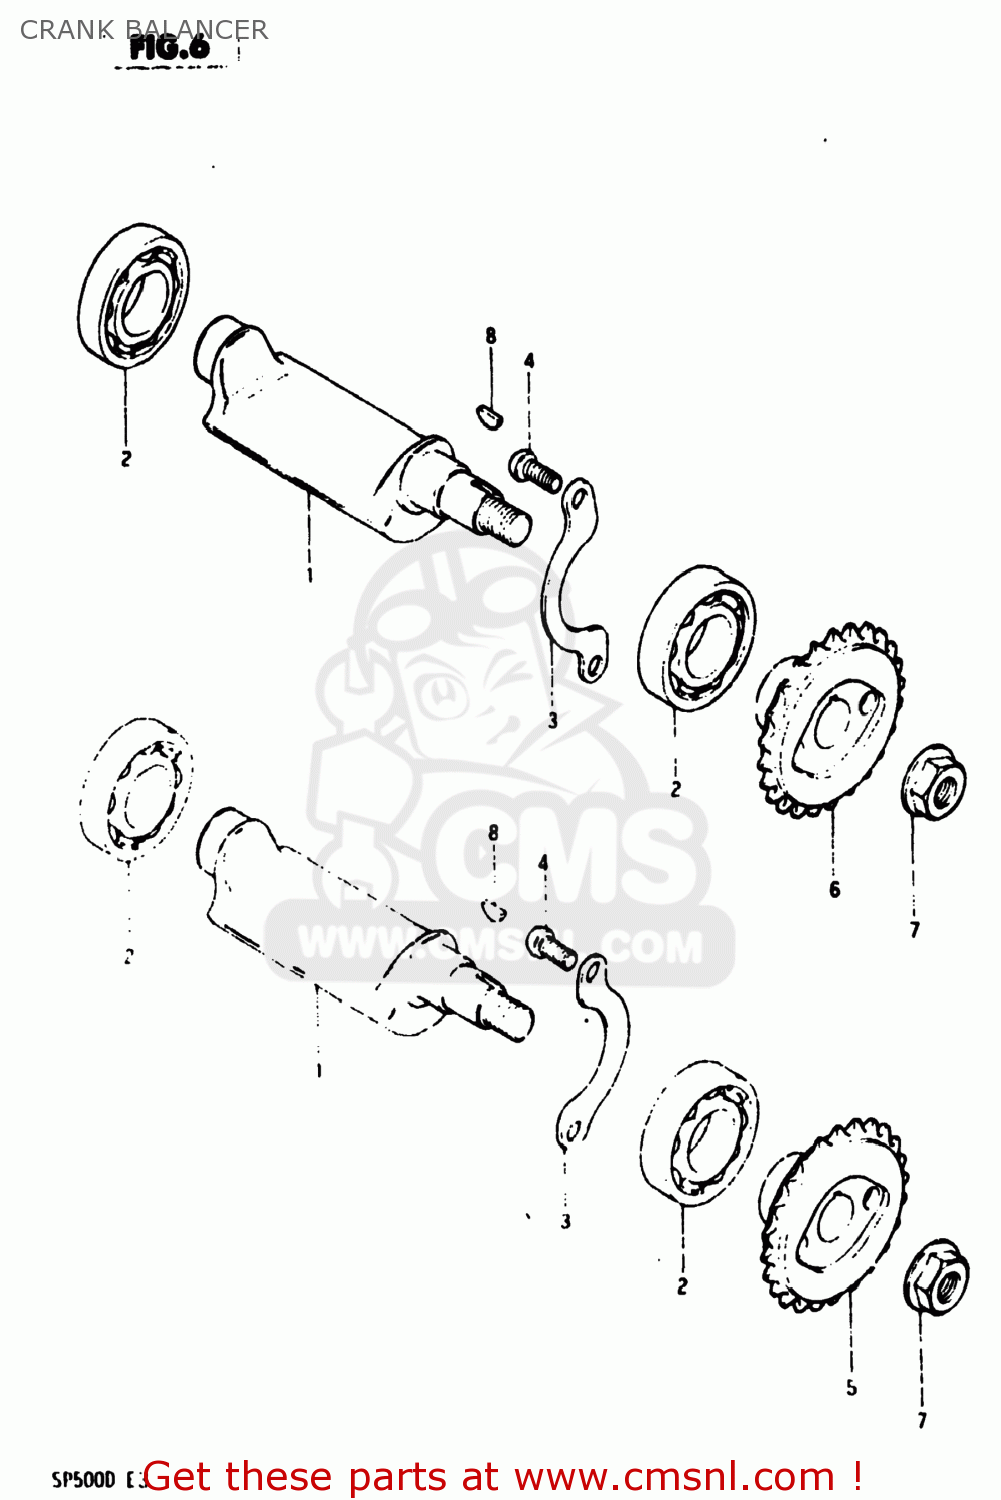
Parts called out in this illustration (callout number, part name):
1	BALANCER,CRANKSHAFT
2	BEARING
3	RETAINER,CRANK BAL BEARING
4	SCREW 6X12
5	SPROCKET,BALANCER DRIVE
6	SPROCKET,BALANCER DRIVE
7	NUT
8	KEY
